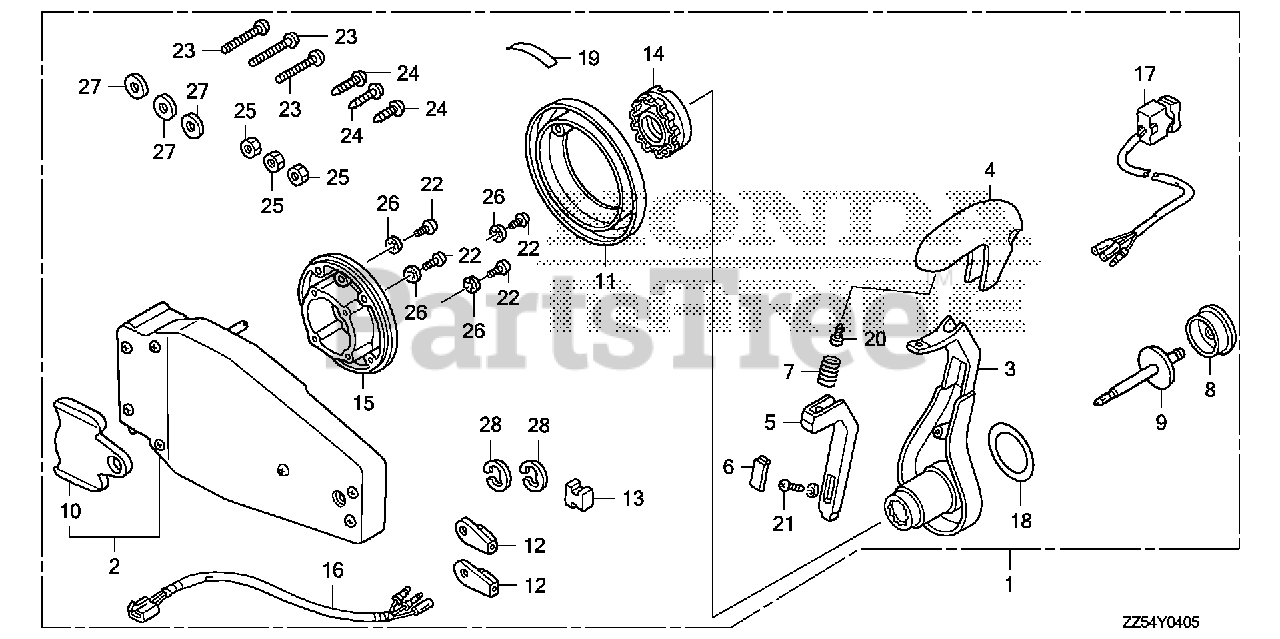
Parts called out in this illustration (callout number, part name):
1	BOX KIT, REMOTE CONTROL (FLUSH MOUNT)(L)
2	HOUSING ASSY., L. (INNER) (FLUSH MOUNT)
3	HANDLE, REMOTE CONTROL
4	COVER, GRIP
5	ARM, NEUTRAL LOCK
6	COVER, LOCK ARM
7	SPRING, NEUTRAL LOCK ARM
8	BUTTON, THROTTLE
9	SHAFT, THROTTLE BUTTON
10	PLATE, DWELL
11	COVER ASSY.
12	TERMINAL, CABLE
13	SPACER, CABLE CLAMP
14	HOLDER, NEUTRAL LOCK
15	BASE
16	SUB-HARNESS ASSY., POWER TRIM-TILT (C)
17	SWITCH ASSY., POWER TRIM-TILT (C)
18	MARK, HANDLE FLUSH MOUNT
19	MARK, FLUSH MOUNT
20	SCREW, PAN (5X16)
21	SCREW, TRUSS (4X12)
22	SCREW, PAN (5X30)
23	SCREW, PAN (6X35)
24	SCREW, TAPPING (6X30)
25	NUT, HEX. (6MM)
26	WASHER, LOCK (5MM)
27	WASHER, PLAIN (6MM)
28	E-RING (6MM)
